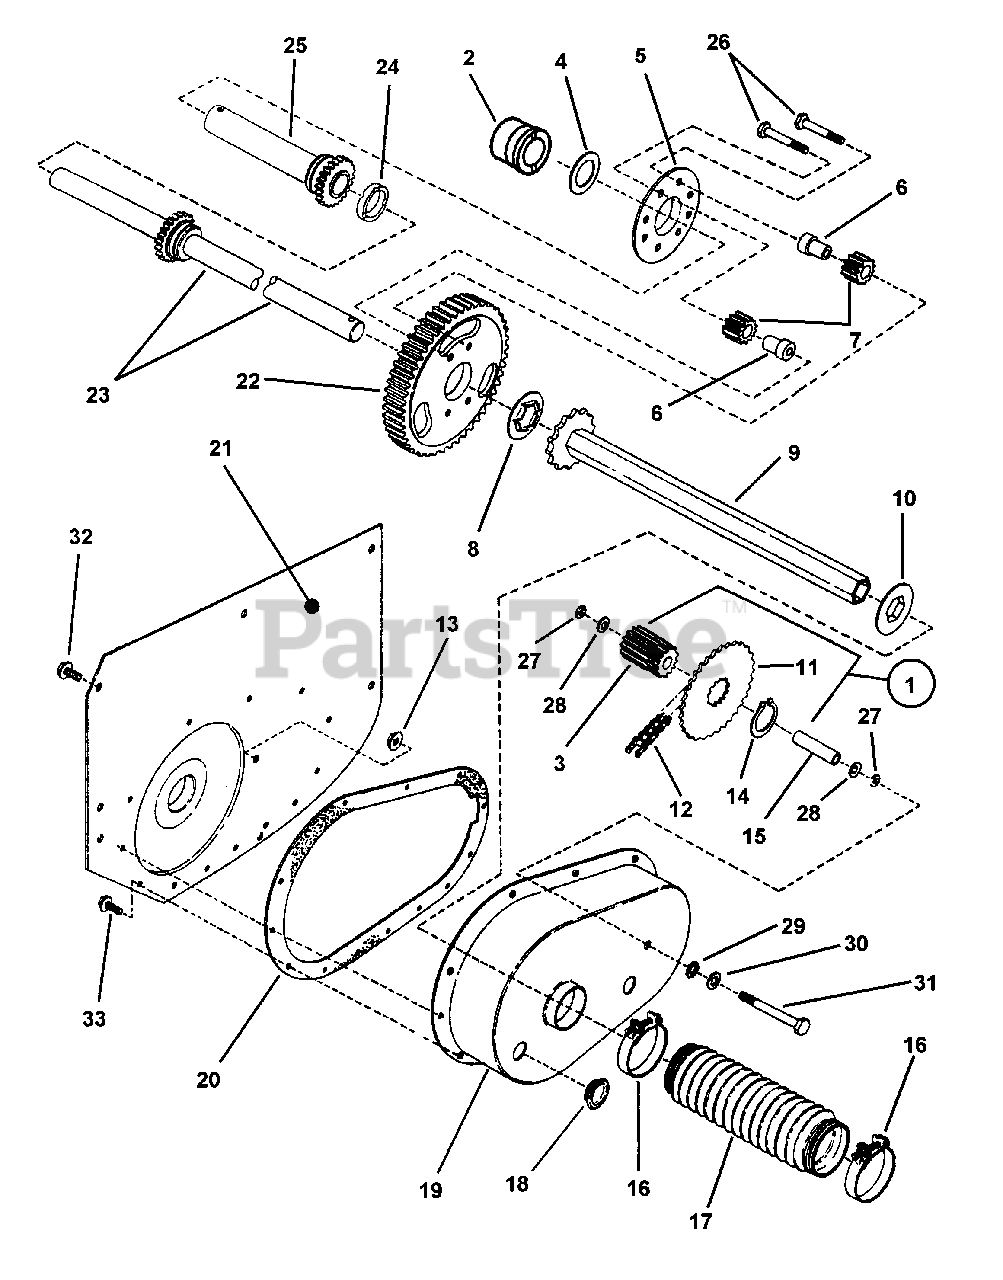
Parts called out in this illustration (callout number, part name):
1	ASSEMBLY, Gear/Sprocket
2	BEARING, Axle (Right Hand Fender)
3	GEAR 11 Teeth
4	WASHER, Thrust
5	PLATE, Differential
6	SPACER, Pinion
7	GEARS, Differential Pinion (12T)
8	WASHER, Thrust
9	ASSEMBLY, Drive Hex Tube
10	WASHER, Nylon
11	SPROCKET (34T)
12	CHAIN, 46 Pitch (#35)
13	NUT, 5/16-24 Hex Flange Lock
14	RING, Retaining
15	SPACER
16	CLAMP, Boot
17	BOOT, Oil Seal
18	PLUG, Oil Fill & Check
19	CASE, Transmission
20	GASKET, Transmission Case
21	FENDER, Right Hand (1.62" hole)
22	GEAR, 63 Teeth-10 Pitch
23	AXLE, Long
24	SPACER, Differential (1.25" ID x .425 Wide)
25	AXLE, Short
26	SCREW, 5/16-24 x 1-5/8" Hex Cap Special Lock
27	O-RING, 5/16"
28	WASHER, Belleville
29	WASHER, 5/16 External Tooth Lock
30	WASHER, 5/16 Flat
31	BOLT, 5/16-24 x 2-5/8" Idler
32	SCREW, 5/16-18 x 5/8" Self-Tap
33	SCREW, 1/4-20 x 5/8" Self-Tap
